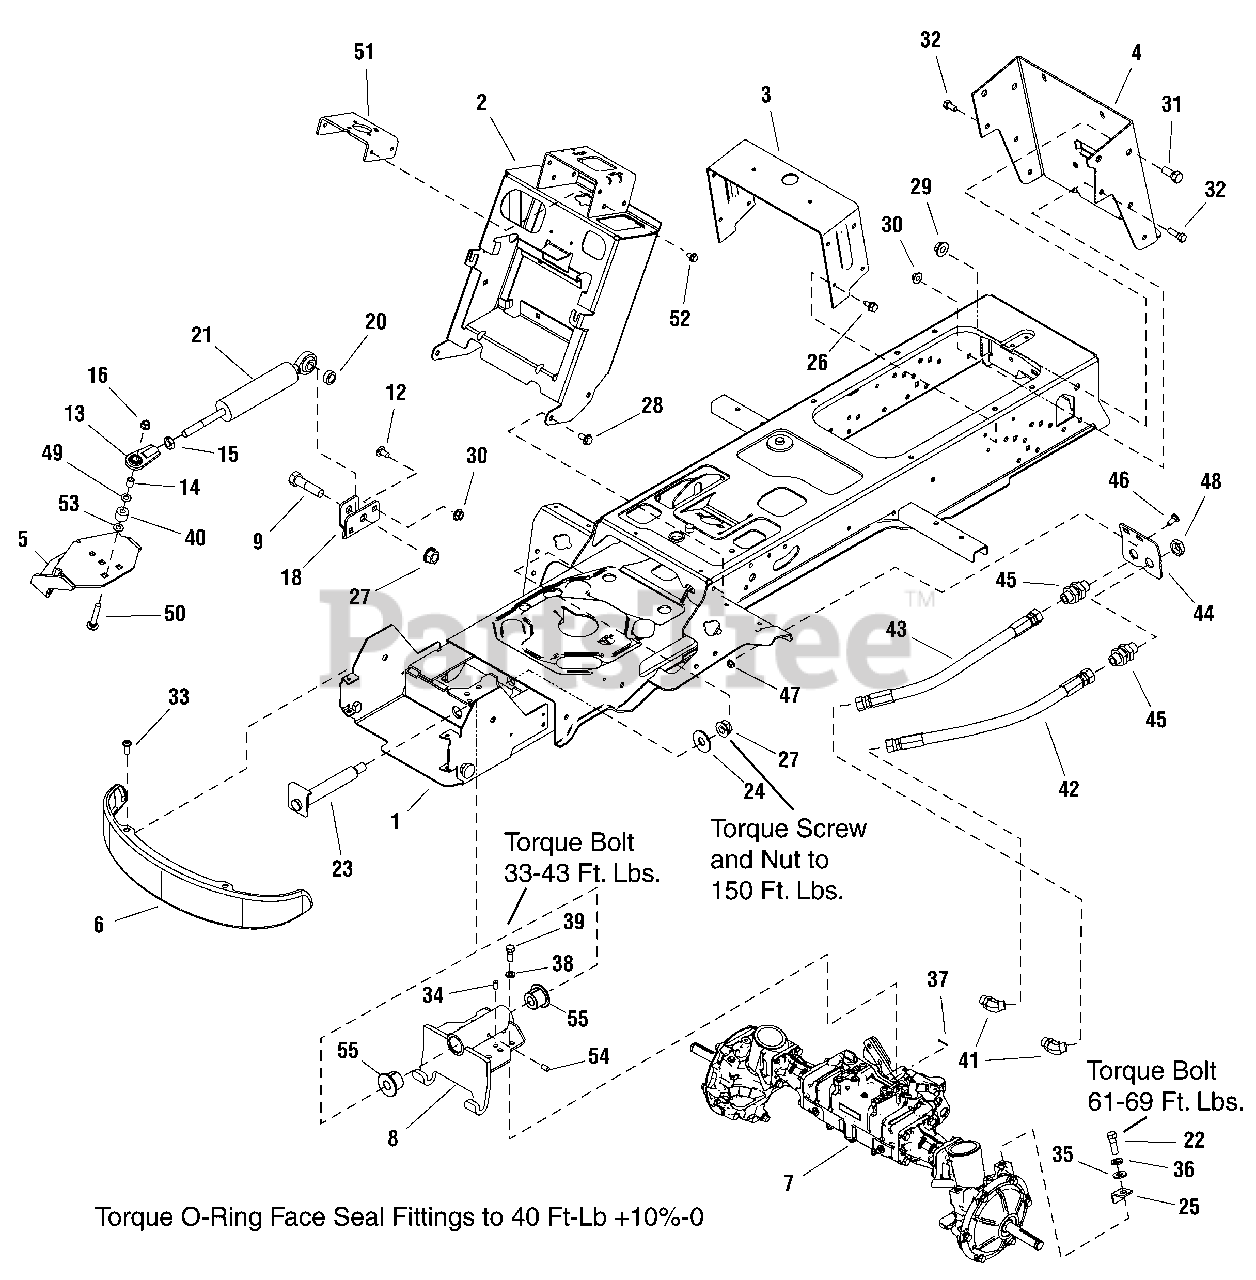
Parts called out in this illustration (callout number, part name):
1	FRAME ASSEMBLY, Front & Rear 4WD
2	TOWER & SUPPORT ASSEMBLY
3	SUPPORT, Seat Deck
4	BACKPLATE, Hitch
5	BRACKET ASSEMBLY, Steering 4WD
6	BUMPER, 4GA
7	AXLE ASSEMBLY, Front
8	PIVOT ASSEMBLY, Axle
9	CAPSCREW, Hex Head, 5/8-11 x 2-1/2 G5
12	BOLT, Carriage, 3/9-16 x 3/4, G5
13	JOINT, Ball 1/2-20
15	NUT, Hex Jam, 1/2-20
16	NUT, Hex Flange, 3/8-16
18	BRACKET, Cylinder Mounting
21	CYLINDER, Hydraulic Steering
22	CAPSCREW, Hex Head, M12-1-3/4 x 35
23	SHAFT & BRACKET ASSEMBLY, Axle Pivot
24	WASHER, 5/8
25	STOP, "L" Steering
26	SCREW, Hex Washer Head Taptite, 5/16-18 x 3/4
27	NUT, Hex Flange 5/8-11 Two-Way Lock
28	SCREW, Hex Washer head, Taptite, 3/8-16 x 3/4
29	NUT, Hex Flange 1/2-13 Whiz Lock
30	NUT, Hex Flange 3/8-16 Whiz Lock
31	CAPSCREW, Hex Head 1/2-13 x 1 G5
32	CAPSCREW, Hex Head 3/8-16 x 1 G5
33	SCREW, Truss Head Torx Drive 5/16-18 x 7/8
34	PIN, Dowel
35	WASHER, 1/2
36	LOCKWASHER, Spring, 1/2
37	PIN, Cotter
38	LOCKWASHER, Spring
39	CAPSCREW, Hex Head
40	SPACER, Powdered Metal
41	FITTING, Hose Elbow, 45 Degree, 13/16-16 x 3/4-16
42	HOSE ASSEMBLY, Hydraulic
43	HOSE ASSEMBLY, Hydraulic
44	BRACKET, Hose Mounting 10GA
45	FITTING, Bulkhead Union 13/16-16
46	BOLT, Carriage, 5/16-18 x 3/4, G5
47	NUT, Hex KEPS, 5/16-18
48	NUT, Jam 13/16-16
49	WASHER, 3/8
50	BOLT, Carriage, 3/8-16 X 2 1/4
51	SUPPORT, Steering Unit 7GA
52	CAPSCREW, Hex Washer Head Taptite 5/16-18 x 1/2
53	PUSHNUT, 3/8
54	FITTING, Lube
